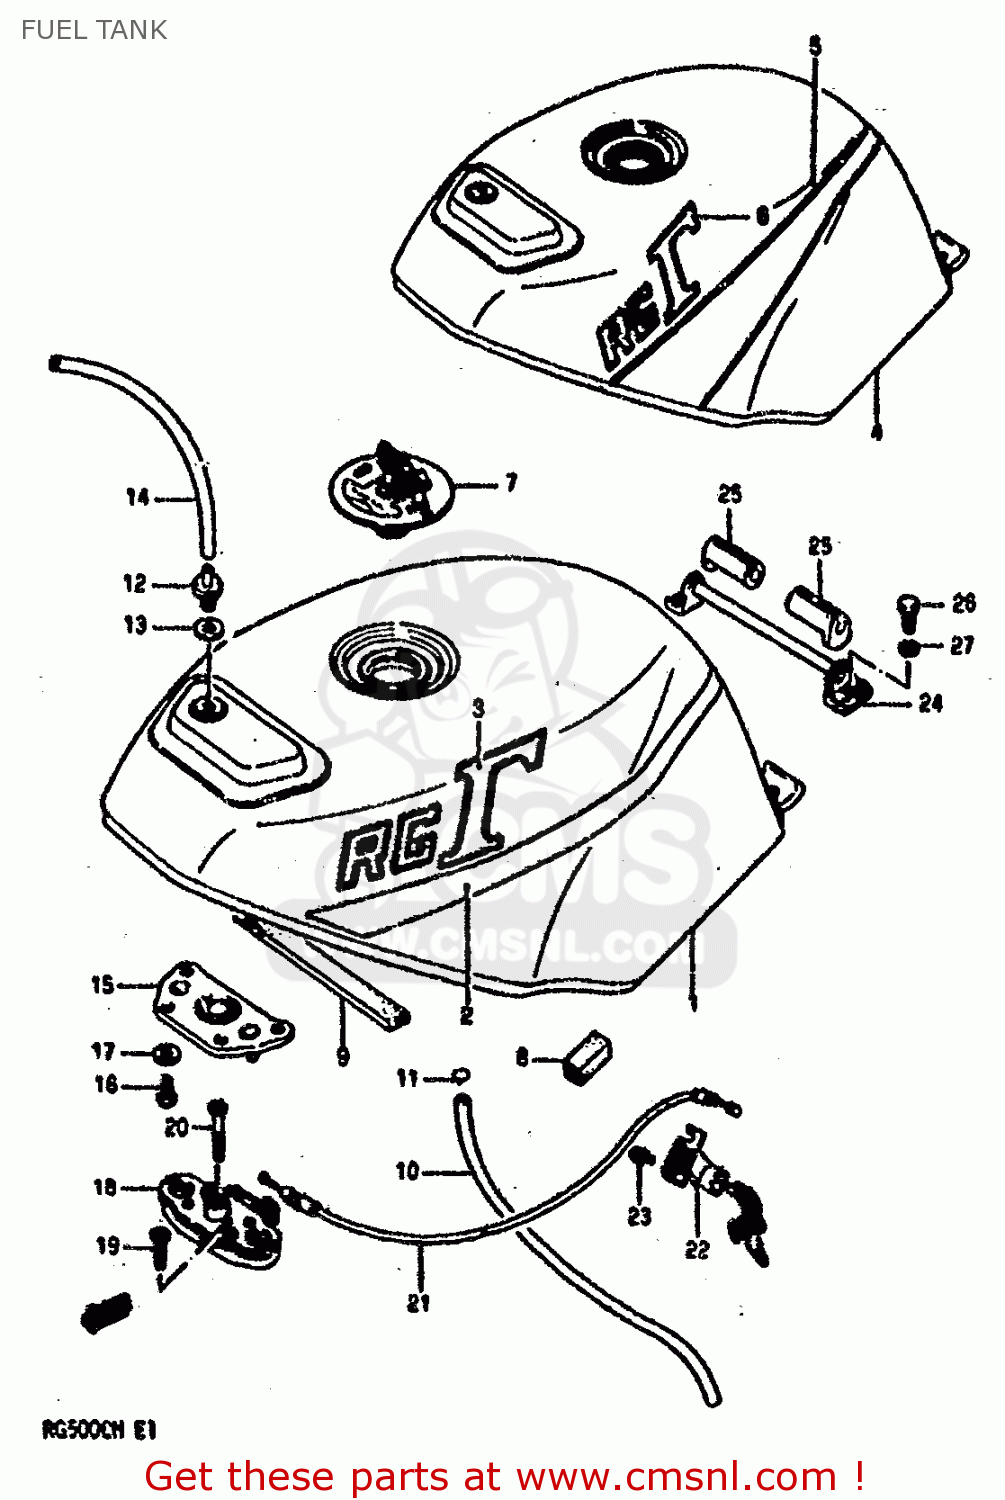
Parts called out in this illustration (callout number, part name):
1	TANK ASSY,FUEL
2	TAPE SET,FUEL TANK (BLUE)
3	EMBLEM
4	TANK ASSY,FUEL
5	TAPE SET,FUEL TANK
6	EMBLEM
7	CAP SET,FUEL TANK
8	CUSHION,FUEL TANK SIDE
9	CUSHION,AIR CLEANER
10	HOSE,FUEL
11	CLIP
12	PLUG, FUEL TANK BREATHER
13	GASKET(12.5X20X2.5) (NAS)
14	HOSE
15	PLATE,TANK LOCK
16	SCREW 6X12
17	WASHER,LOCK
18	BRACKET,SEAT SUPPORT,RIGHT
19	SCREW
20	SCREW,CENTER
21	CABLE,TANK LOCK
22	LOCK, SEAT
23	BOLT
24	PIPE,FUEL TANK REAR
25	CUSHION,FUEL TANK RR
26	SCREW
27	WASHER,LOCK
